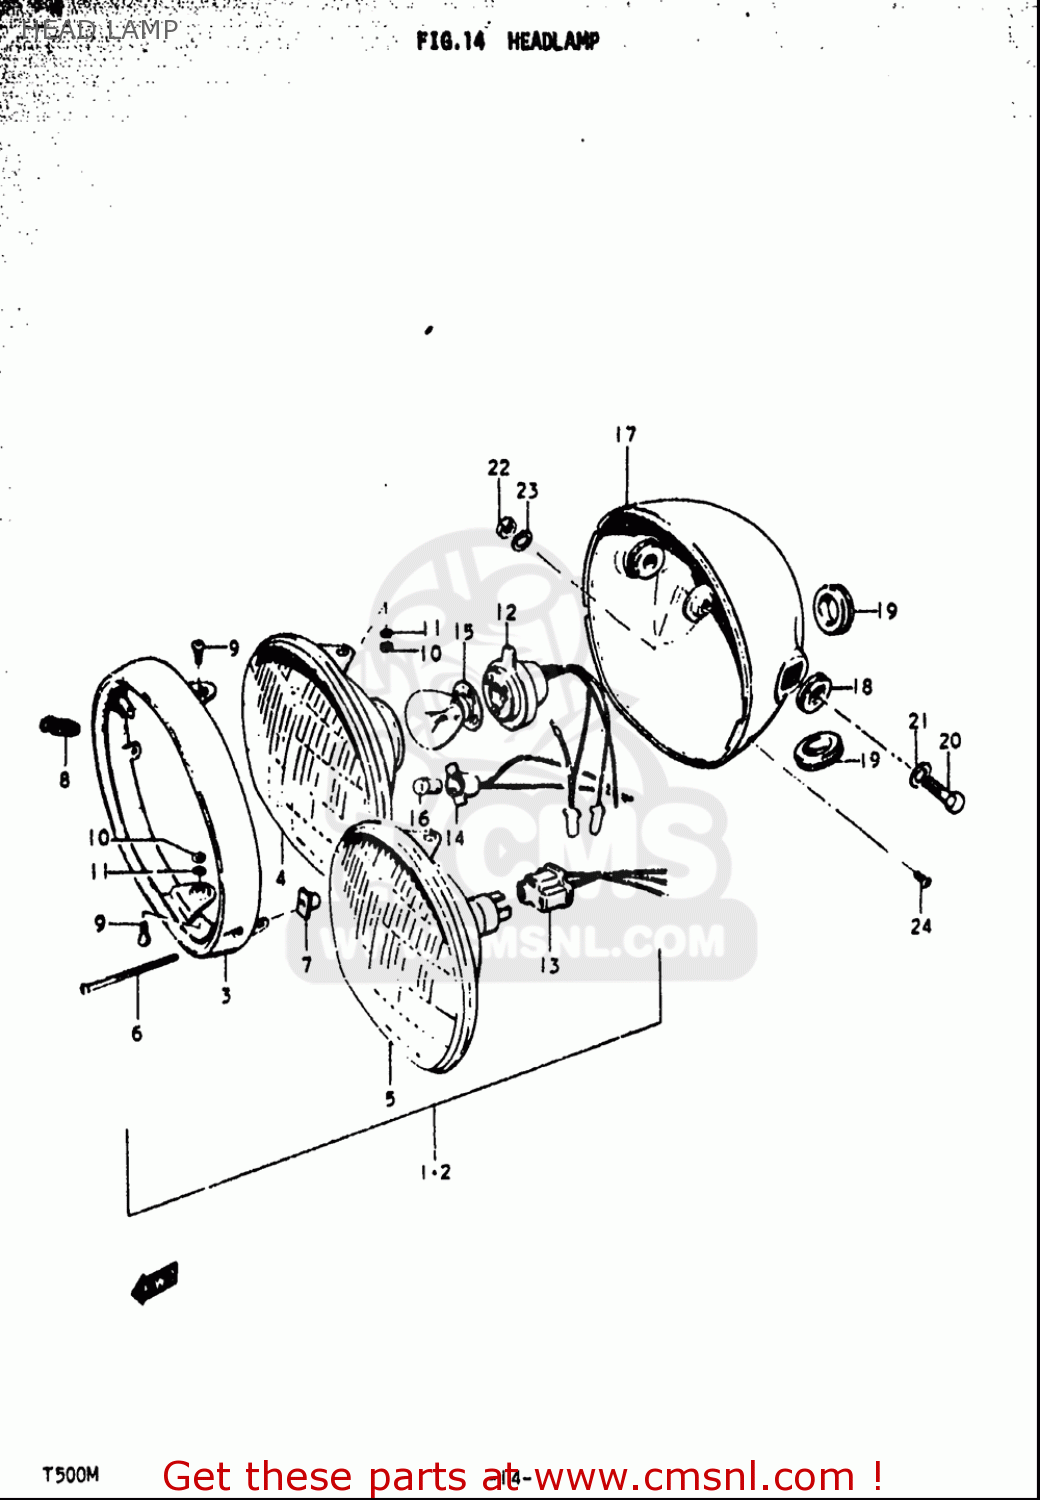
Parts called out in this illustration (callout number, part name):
7	NUT
8	SPRING,HEADLAMP ADJUST
10	NUT
11	WASHER,LOCK
14	SOCKET
16	BULB(12V3.4W,STANLEY,A72A)
20	BOLT
21	WASHER
22	NUT
23	WASHER,LOCK
24	SCREW
